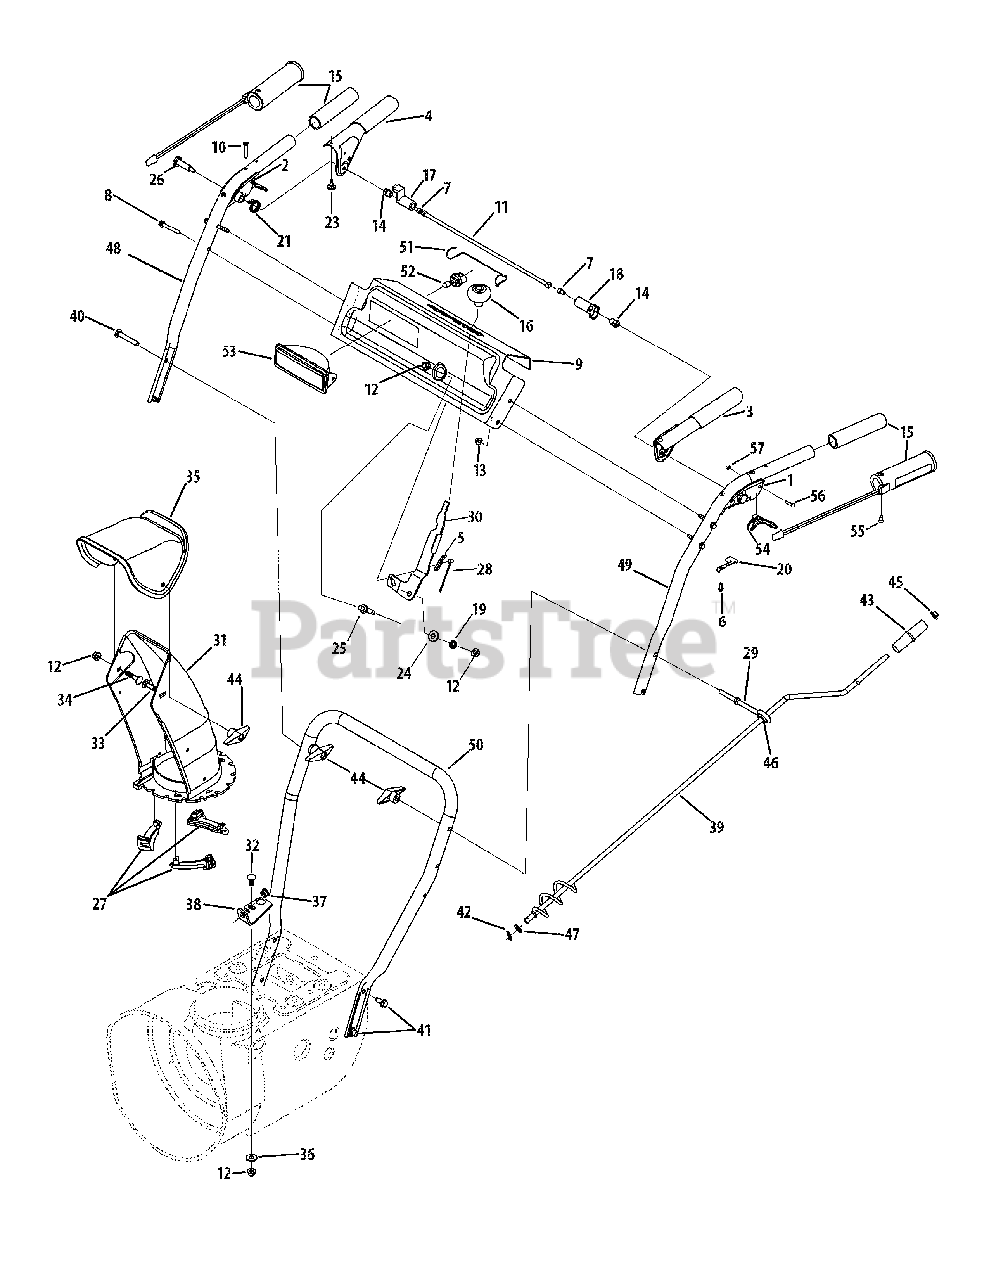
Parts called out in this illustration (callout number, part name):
1	Handle Assembly, Clutch Lock LH
2	Handle Assembly, Clutch Lock RH
3	Handle Assembly, Engage LH
4	Handle Assembly, Engage RH
5	Click Pin
6	Screw, #8-16 x .50
7	Screw, 1/4-20, 1.50
8	Hex Screw, 1/4-20, 1.50
10	Machine Screw, #10-24, 1.375
11	Pivot Rod
12	Flange Lock Nut, 5/16-18
13	Flange Lock Nut, 1/4-20
14	Shoulder Hex Nut, 1/4-20
15	Heated Grip
16	Shift Knob
17	Lock Plate
18	Clutch Lock Cam
19	Spring, .39 x .60 x .88
20	Clutch Lock Spring
21	Torsion Spring, 0.8156 ID x .3038
22	Wire Harness
23	Rubber Bumper, .62 OD x .22
24	Flat Washer, .385 x .870 x .092
25	Shoulder Bolt, 5/16-18 x 0.905
26	Shoulder Screw, .43 x 1.3, 1/4-20
27	Chute Flange Keeper
28	Speed Selector Cable
29	Chute Crank Eye Bolt
30	Shift Lever
31	Lower Chute, 5.0 Dia
32	Carriage Bolt, 5/16-18, 1.0
33	Carriage Bolt, 5/16-18, 1.0
34	Carriage Bolt, 5/16-18, .750
35	Upper Chute w/ Label
36	Washer, .349 x .879 x .063
37	Plastic Bushing, .380
38	Chute Crank Bracket
39	Chute Crank Assembly
40	Carriage Screw, 5/16-18, 2.25
41	Screw, 5/16-18, 0.75, Gr5
42	Cotter Pin, .072 x 1.13
43	Crank Knob, 1.0 Dia x 3.2
44	Wing Knob, 5/16-18
45	Push Cap, 3/8 Rod
46	Grommet, .44ID x .94 OD x .50
47	Flat Washer, .375 x .738 x .063
51	Lens Retainer
52	Halogen Lamp,12V, 27W
53	Lamp Lens Assembly
54	Steering Triggers
55	AB Screw
57	E-Ring
